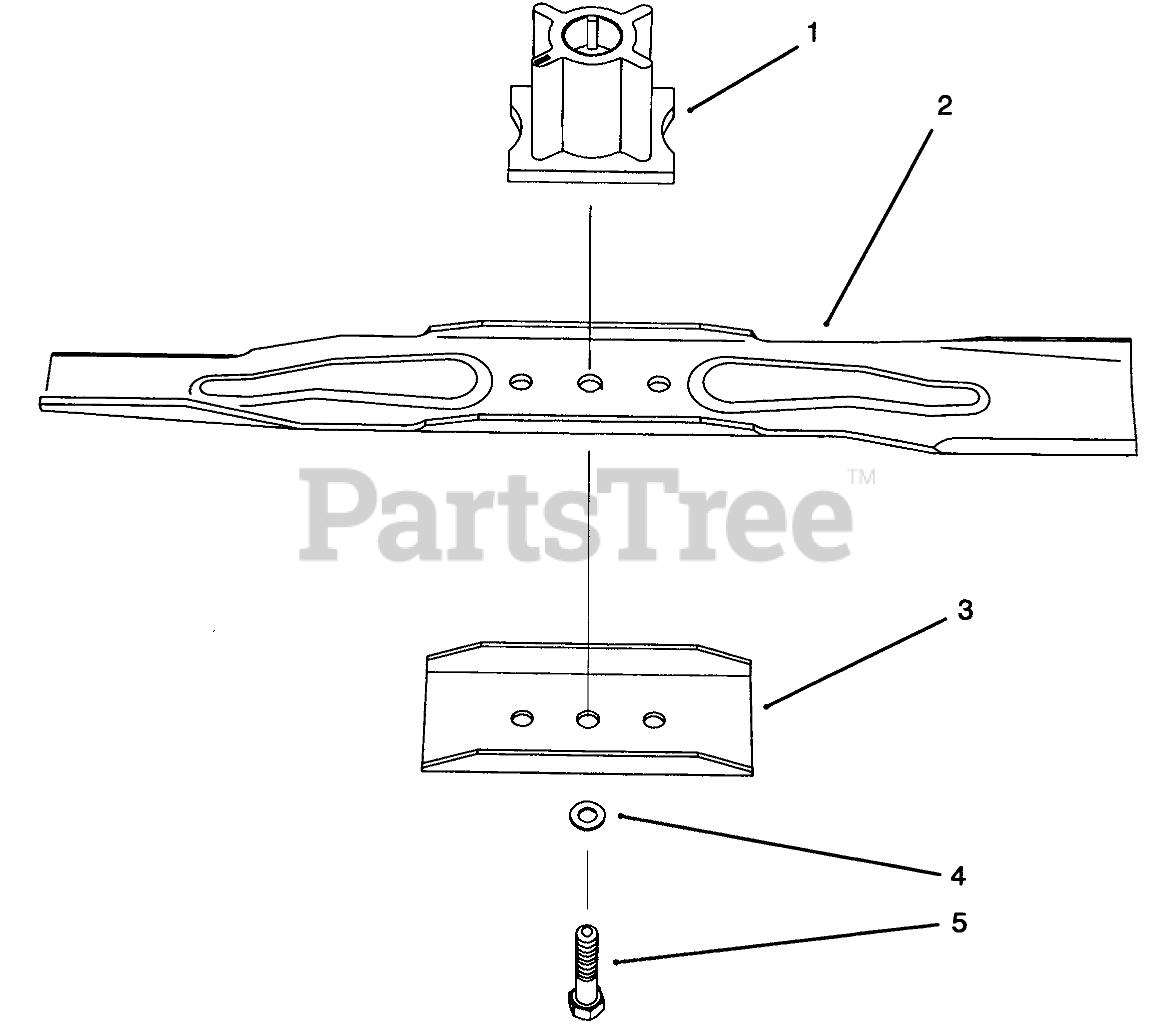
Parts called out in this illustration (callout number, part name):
1	BLADE RETAINER - 25 MM
2	Blade
3	Stiffener
4	WASHER-LOCK
5	BOLT-BLADE
